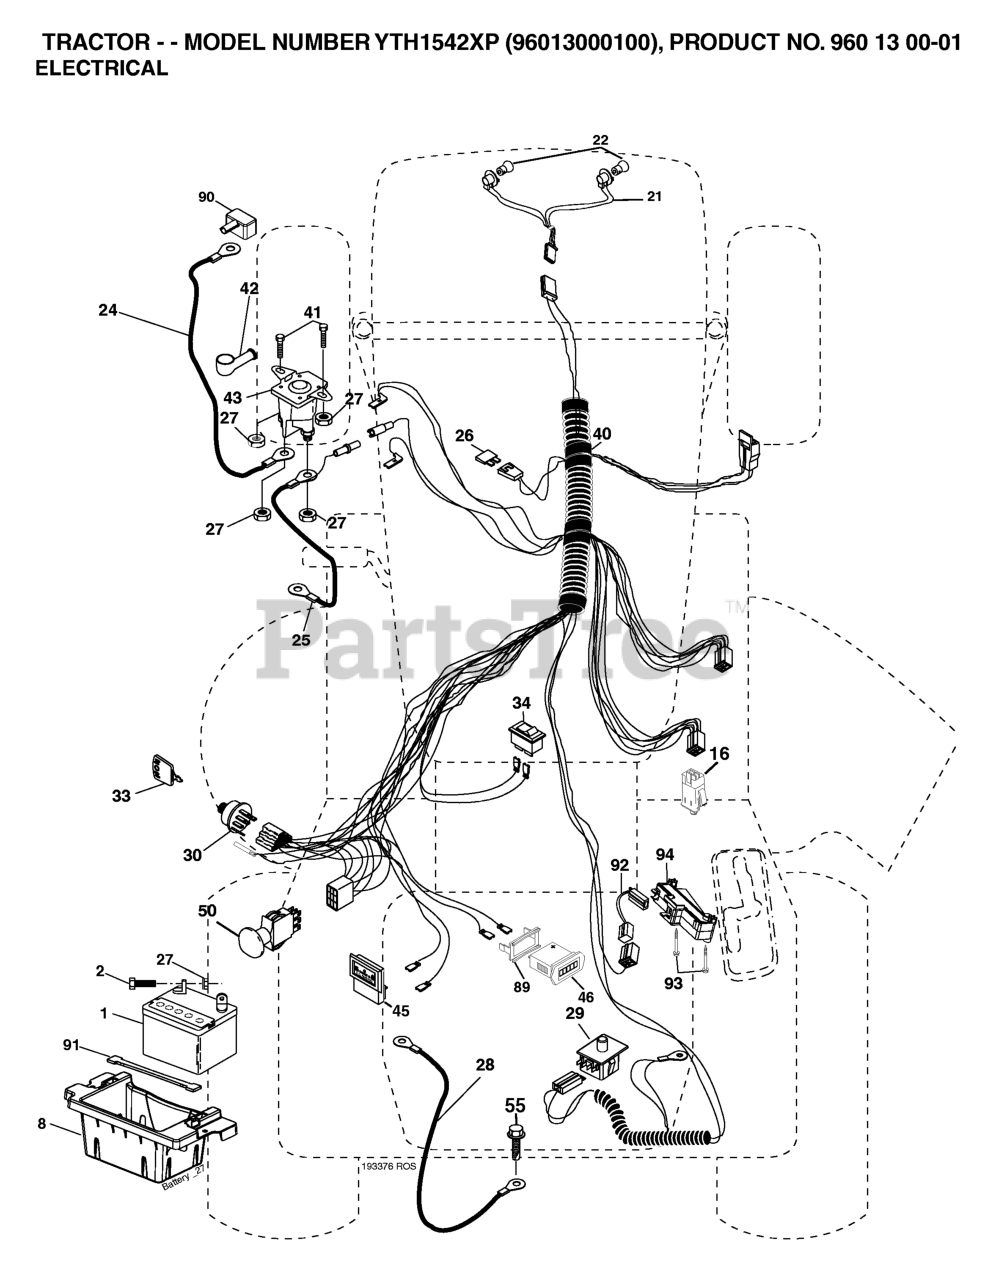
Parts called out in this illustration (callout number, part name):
1	BATTERY 12V .35 AMP
2	BOLT.HEX.1/4.X.3/4.DICHROMATE
8	BOX.BATTERY.MOUNT.FRONT.LT
16	SWITCH INTERLOOK PUSH-IN
21	HARNESS ASSY LIGHT
24	BATTERY CABLE GT
25	CABLE BATTERY 6 GA 22" W/16W
26	FUSE 20AMP
27	NUT
28	CABLE GROUND 6 GA 21" 90T BLK
29	SWITCH.SEAT.DP W/RAMPS
30	SWITCH.IGN.DELTA.W.LGH.ROS
33	KEY MLD GEN DELTA
40	HARNESS.IGN.ELECT.STL
41	BOLT
42	TERMINAL COVER
43	SOLENOID
46	HOUR METER
50	RP.PTO.SWITCH.8 TERMINAL.BLACK
55	Screw 5/16-18 x 1/2 Hex, Self Tapping 5/16-18 x 1/2
89	BRACKET SNAP-IN HOURMETER
90	COVER TERMINAL
91	COVER TERMINAL
92	HARNESS.PIGTAIL.REVERSE.SWITCH
93	SCREW.PLASTITE
94	MODULE.REVERSE.ROS
